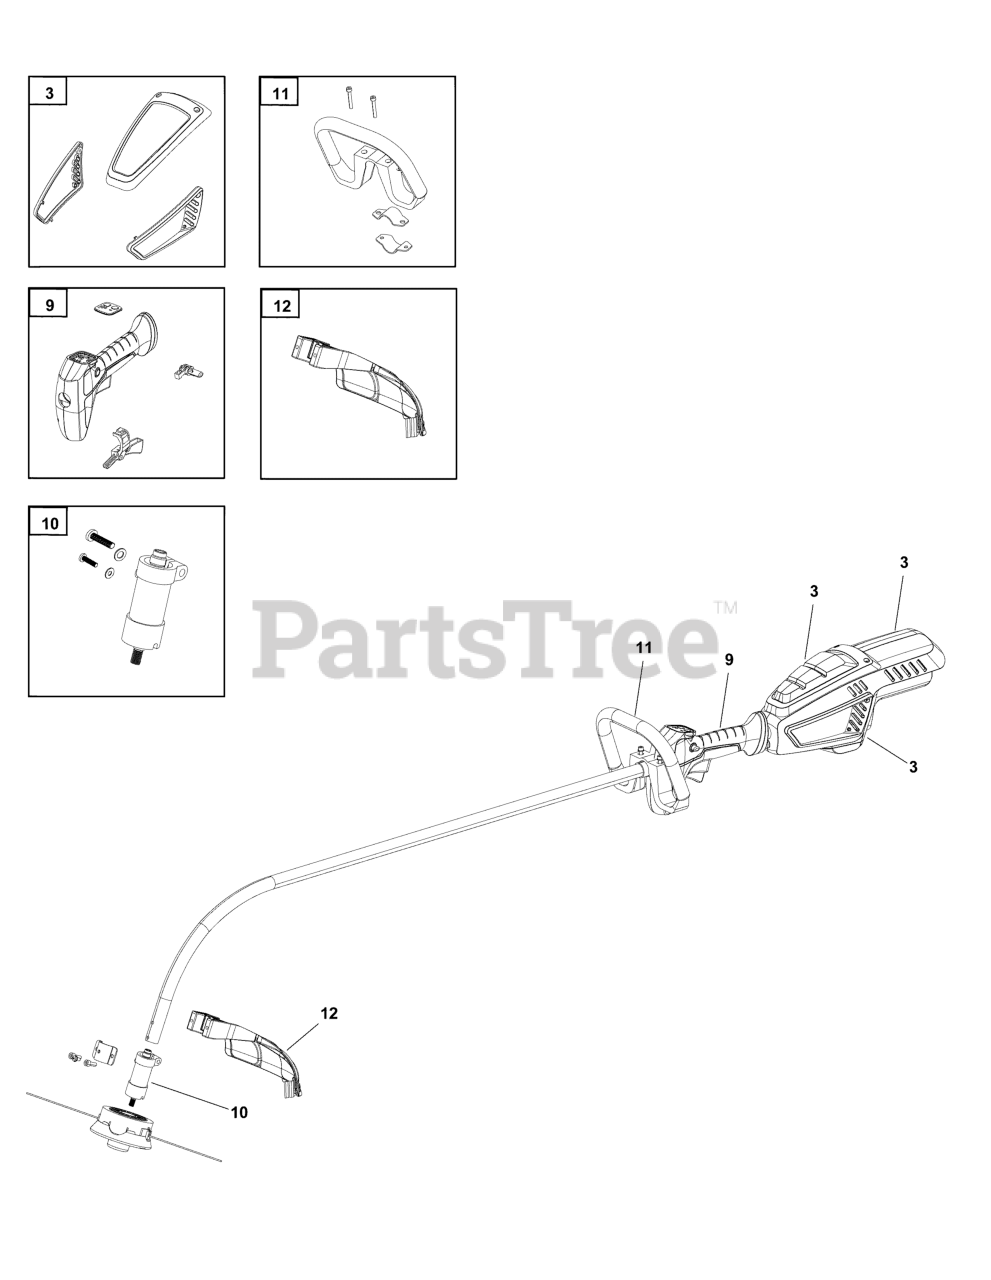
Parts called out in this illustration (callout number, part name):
3	KIT, INSERTS
9	ASSEMBLY, Throttle Handle
10	GEAR HEAD ASSEMBLY
11	HANDLE ASSEMBLY
12	GUARD, Safety
